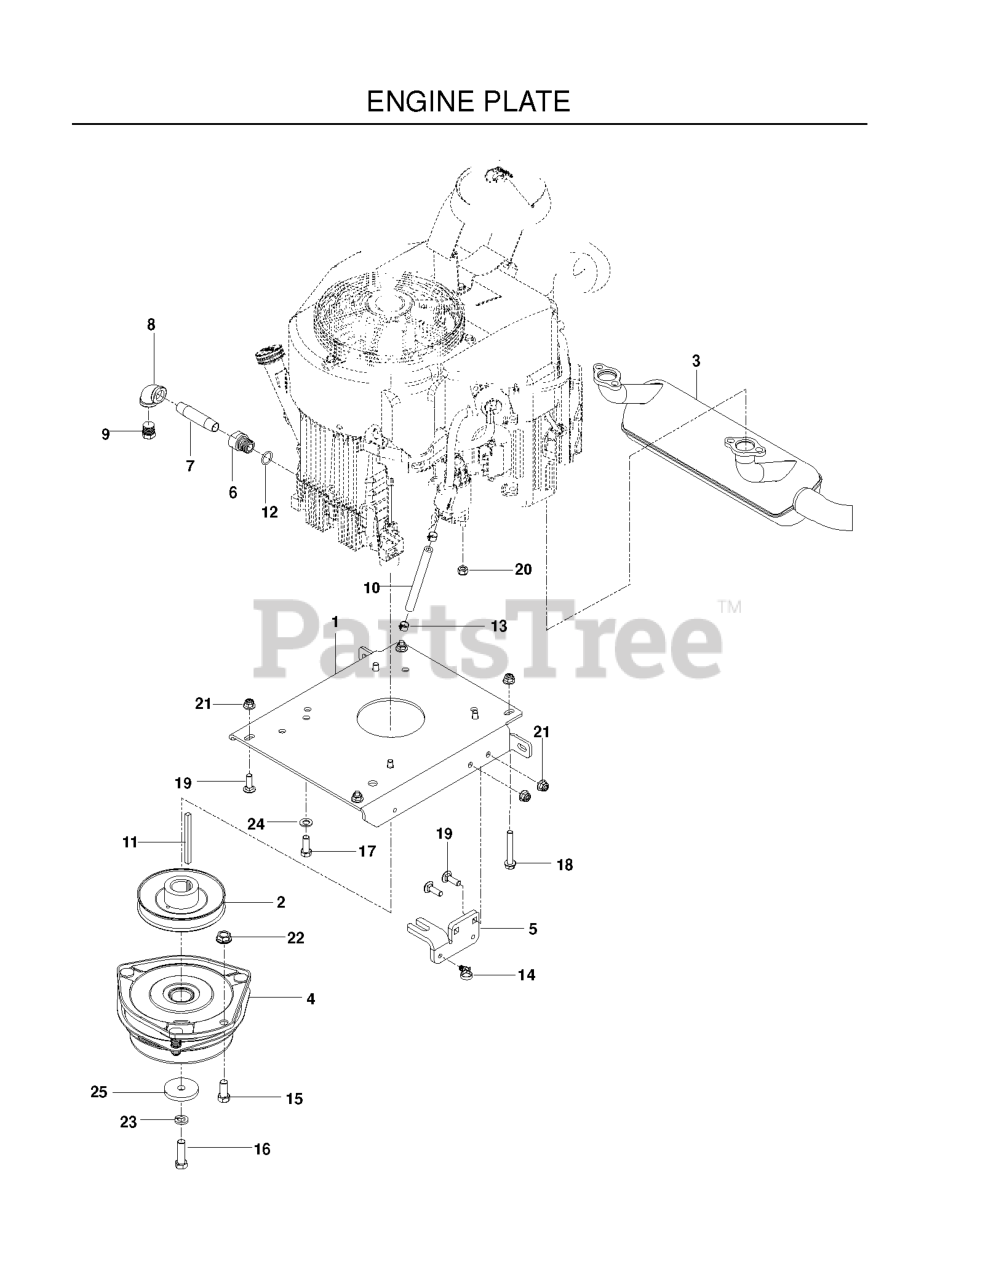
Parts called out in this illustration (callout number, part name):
1	PLATE.ENGINE.BLACK
2	PULLEY, ENGINE
3	MUFFLER, 29HP KAW FX751V-850V
4	CLUTCH, GT3.5
5	STOP, CLUTCH, OGURA
6	ADAPTER, OIL DRAIN
7	PIPE NIPPLE 3/8 X 3
8	90 DEG.ELBOW 3/8NPT
9	PLUG, DRAIN 3/8 NPTF
10	GAS LINE 10"
11	KEY, 1/4 SQ X 3.5
13	HOSE CLAMP
14	TIE WRAP, 8-3/8", W/CLIP
15	HCS 7/16-14 X 1 GR 5 ZD
16	HCS 7/16F X 1 1/2
17	HCS 3/8-16X1.GRD.5.ZD
18	HHFS 5/16-18 X 2.25 GD 5
19	RHSNB 5/16C X 1
20	NUT M8-1.25 TOP NYL GR10 ZD
21	5/16-18 NYLOC FLANGE NUT
22	NUT 7/16C WHIZ
23	WASHER 7/16 LOCK
24	WASHER, 3/8 DISC SPRING SPEC
25	BLADE WASHER
